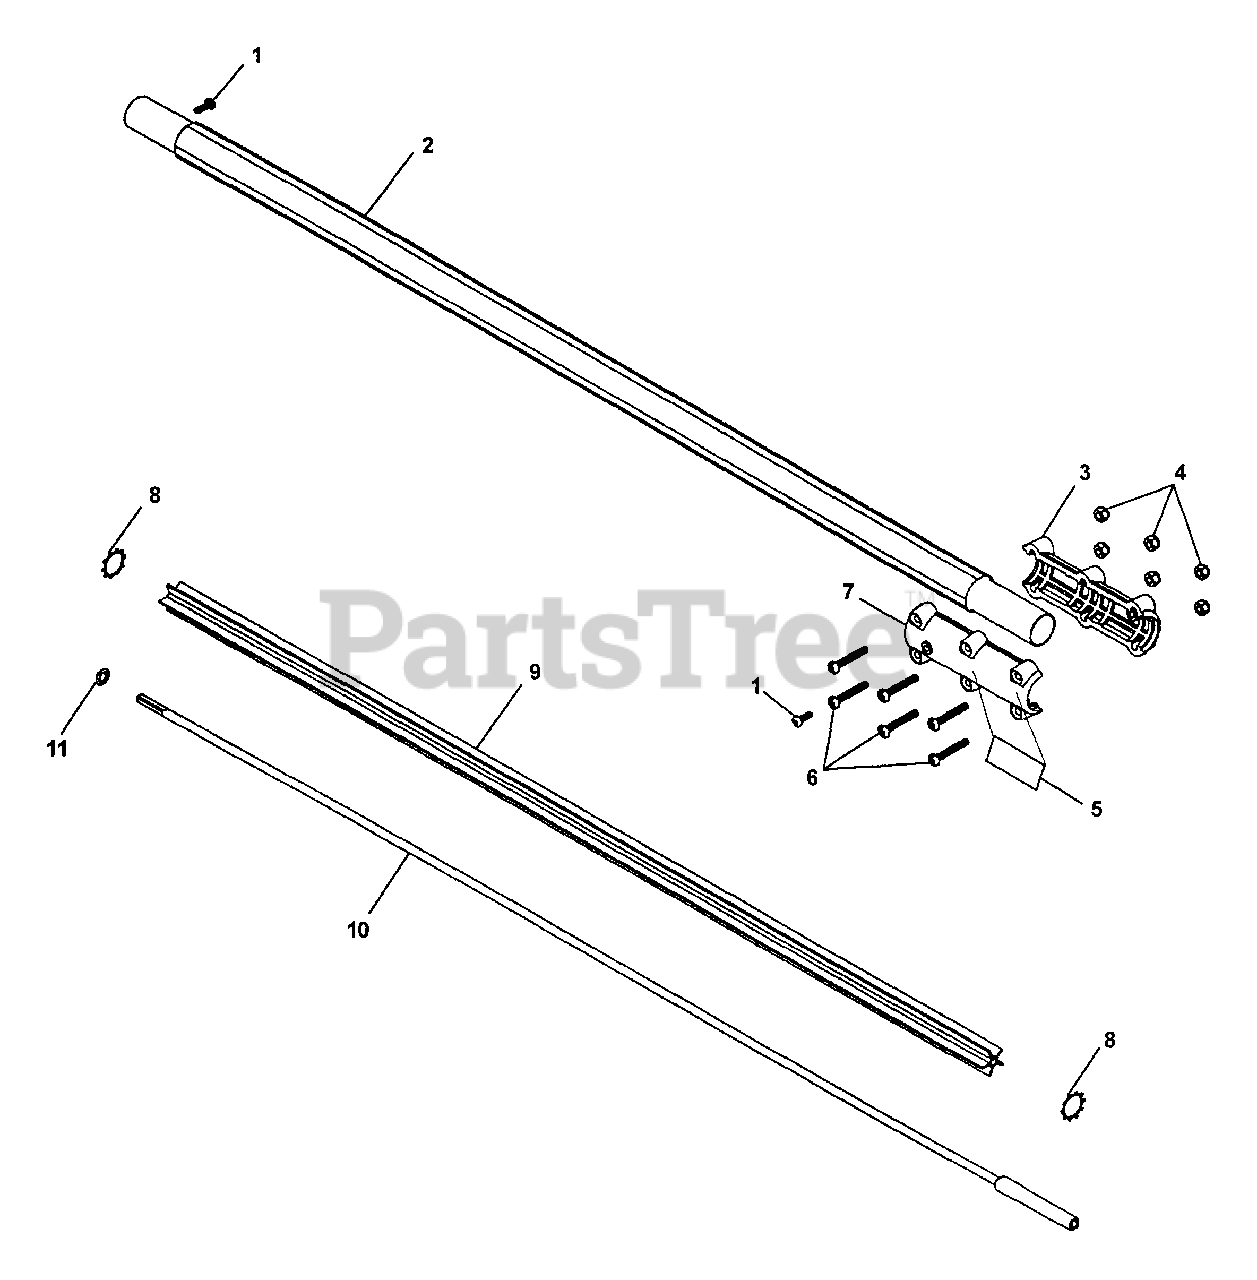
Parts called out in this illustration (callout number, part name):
1	SCREW - TORX PAN HEAD
2	PIPE, MAIN
3	COLLAR, MAIN PIPE - BOLT SIDE
4	NUT, LOCK 10-24 UNC
5	LABEL, CAUTION
6	SCREW, TORX 10-24 UNC 1-1/4
7	COLLAR, MAIN PIPE - NUT SIDE
9	LINER - FLEXIBLE
10	DRIVESHAFT
11	LOCKWASHER - INTERNAL
